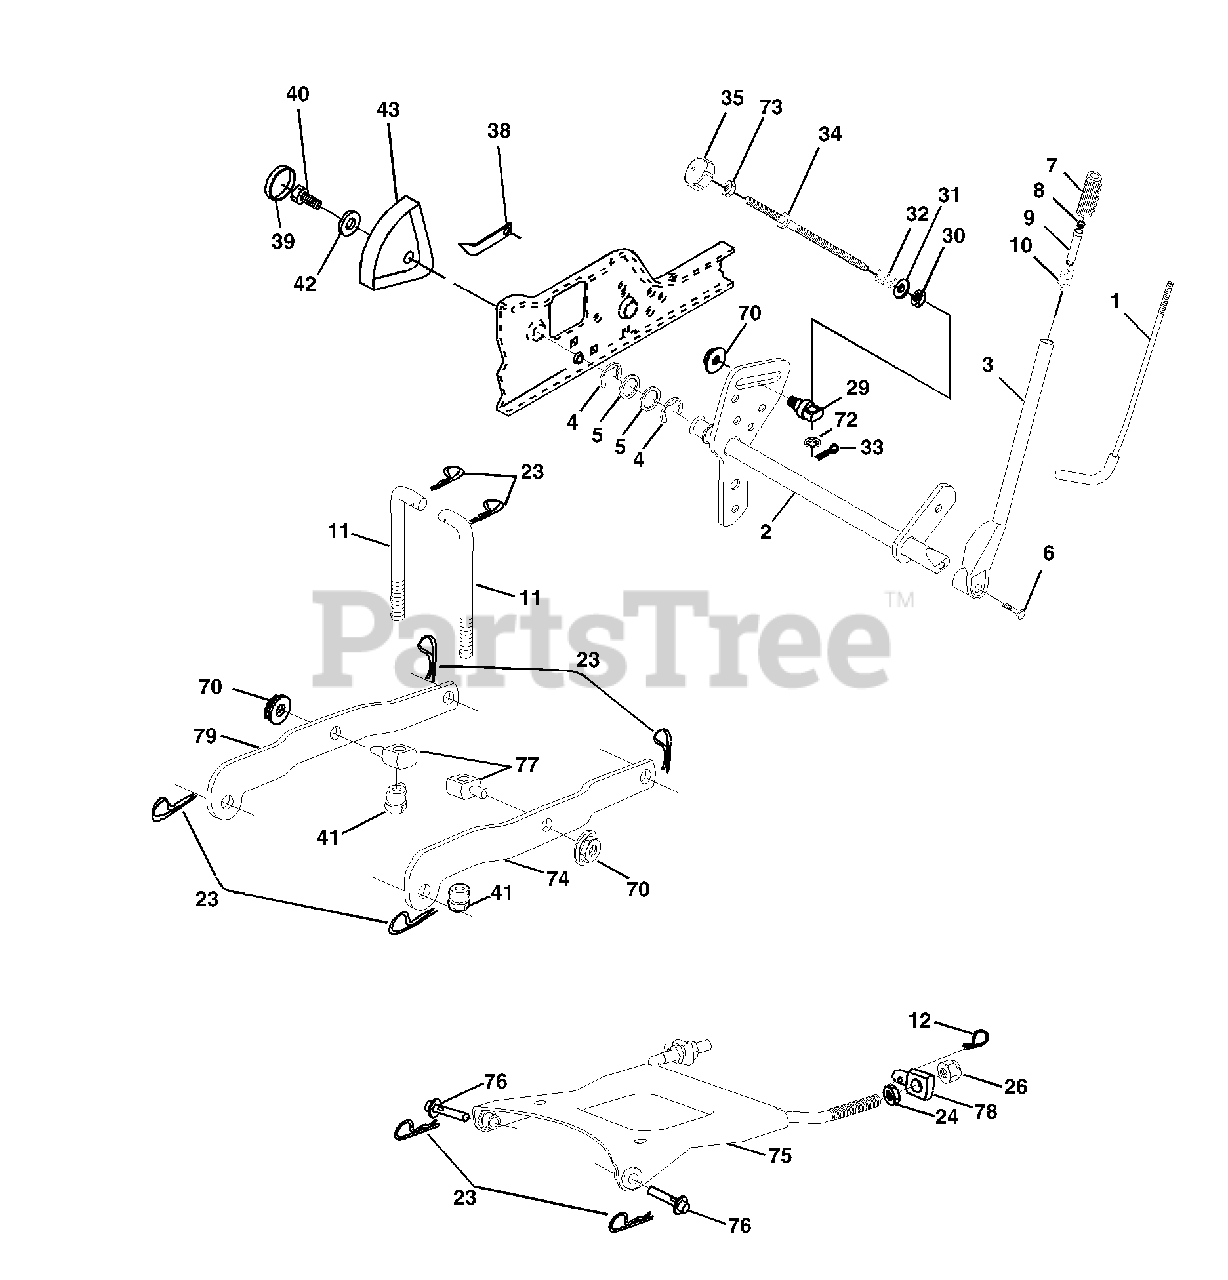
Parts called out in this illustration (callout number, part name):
1	Rod Asm., Lever
2	Shaft Asm., Lift Vgt
3	Lever Asm., Lift Rh
4	E-Ring Truarc #5133-87
5	Washer 29/32 x 1-1/4 x 16 Ga.
6	Bolt, Fin Hex 3/8-16 x 1-1/2
7	Grip, Handle
8	Button, Plunger
9	Plunger, Lever Lift
10	Spring 0.620D x 2.125
11	Link Lift
12	Retainer, Spring
23	Retainer, Spring
24	Nut, Jam Hex 1/2-13 Unc
26	Nut, Lock W/Wsh 1/2-13 Unc
29	Trunnion Infin Height
30	Nut, Special
31	Washer 13/32 x 5/8 x 16 Ga.
32	Spring, Compression Inf Hgt
33	Pin, Cotter 3/32 x 1/2
34	Rod, Adj Lift
35	Knob, Inf 3/8-16 Unc
38	Pointer Height Indicator
39	Plug, Hole Blk. 1.485/1.515 Dia.
40	Screw 5/16-18 x 1
41	Nut, Lift Link 7/16-20
42	Washer 11/32 x 1-1/2 x 10 Ga.
43	Scale, Indicator Height
70	Nut Hex Flange Lock
72	Nut Push Phos & Oil
73	Nut, Hex Jam 3/8-16 Unc
74	Arm Suspension Rear RH
75	Plate, Asm, Susp, Front
76	Pin Flange
77	Trunion Susp Arm
78	Trunnion, Front, Susp
79	Arm, Suspension LH
